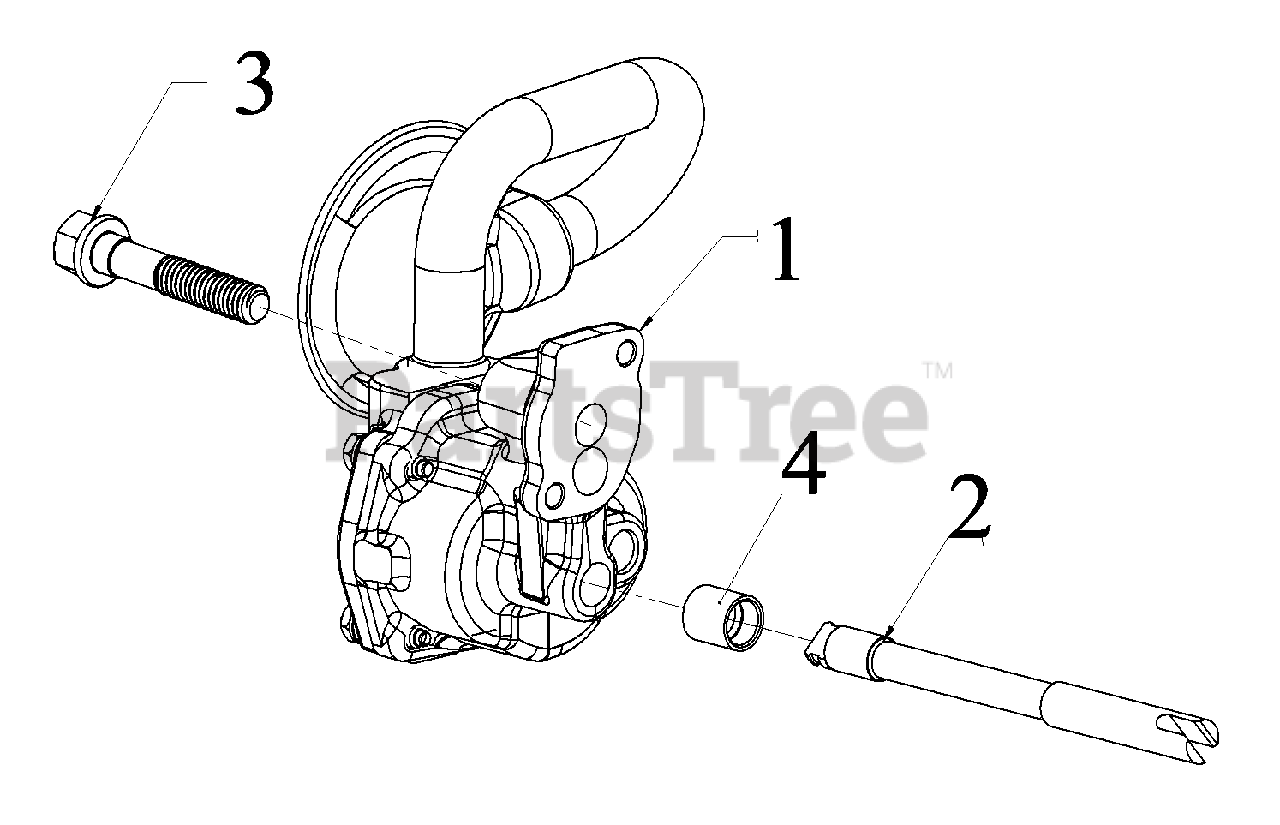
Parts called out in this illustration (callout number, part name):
1	PUMP, OIL
2	SHAFT, OIL PUMP DRIVE
3	BOLT, OIL PUMP
4	RETAINER, OIL PUMP SHAFT
